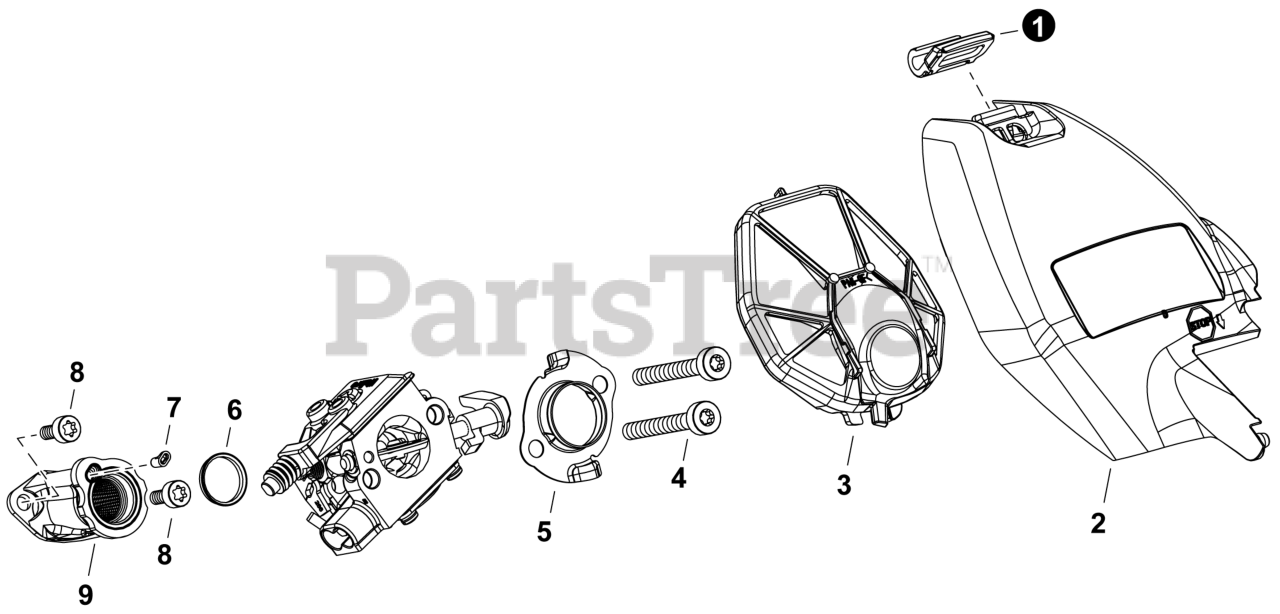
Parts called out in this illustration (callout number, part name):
1	RETAINER, AIR FILTER
2	COVER, AIR FILTER
3	FILTER ASSY, 250 MESH AIR
4	BOLT, TORX 5x40
5	ELBOW, CARBURETOR
6	COLLAR 14
7	COLLAR 3
8	BOLT, TORX 4x10
9	BELLOWS, INTAKE
